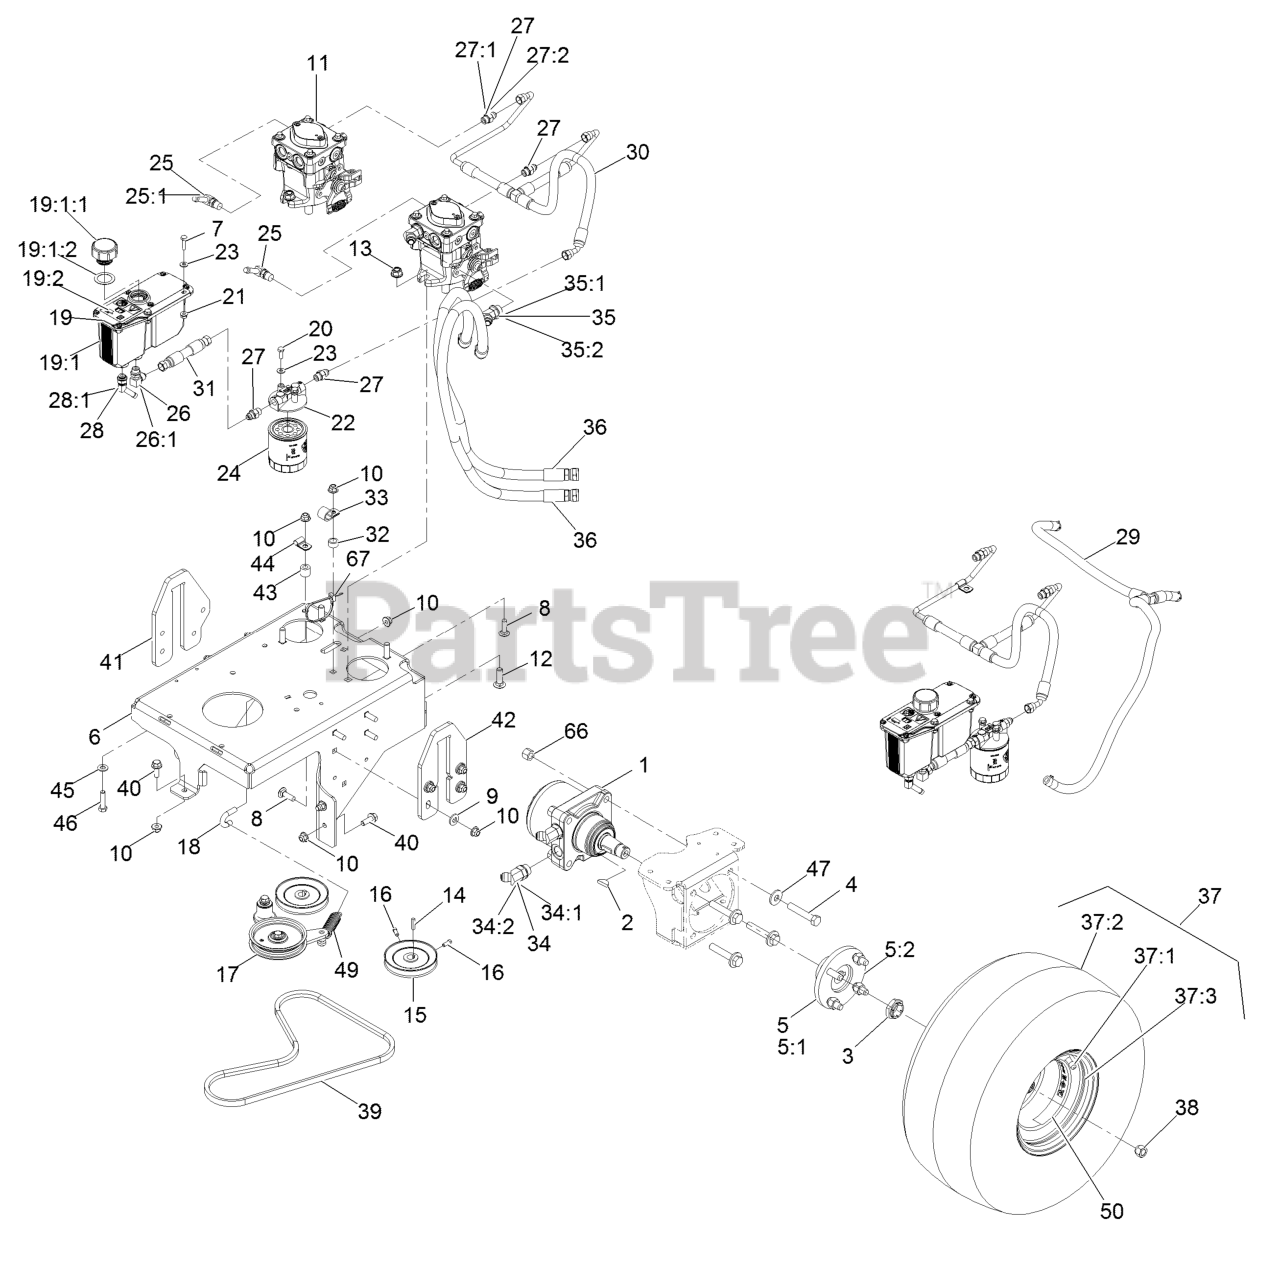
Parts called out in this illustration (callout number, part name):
1	Motor-Wheel
2	Key-Woodruff
3	Locknut
4	Screw-HH
5	Wheel Hub / Stud ASM
5:1	Hub-Wheel
5:2	Stud-Type, Drive
6	Base, Engine [red]
7	Screw-HH
8	Bolt-CARR
9	Washer-Belleville
10	Nut-HF, NI
11	Pump - Hydraulic
12	Bolt-CARR
13	Nut-HF, NI
15	Pulley-Pump
16	Screw-Set
17	Pump Idler ASM
18	Anchor, Spring
19	Reservoir ASM
19:1	Reservoir-HYD
19:1:1	Cap-Reservoir, HYD
19:1:2	Gasket-Cap
19:2	Decal-Warning
20	Screw-HH
21	Nut-HHF
22	Head-Filter
23	Washer-Flat
24	Element, Oil Filter
25	Fitting-Elbow, 90
25:1	O-Ring
26	Fitting-Elbow, 90 DEG
26:1	O-Ring
27	Fitting-Straight
27:1	O-Ring
28	Fitting-Barbed, 45 DEG
28:1	O-Ring
29	Tank Hose ASM
30	Hose Assembly - Charge
31	HYD Hose ASM
32	Spacer-Wheel
33	Clip-Loom
34	Fitting-HYD, 45 DEG
35	Fitting-HYD, 45 DEG
36	HYD Hose ASM
37	Wheel/Tire ASM
37:1	Rim-8 Inch
37:3	Stem-Valve
38	Nut-Lug
39	Belt-V, Lower PTO
40	Screw-HHF
41	Plate-Lift, RH
42	Plate, Lift LH
44	Clip-Tube
45	Washer-Flat
46	Screw-HH
47	Washer-Spring
49	Spring-Extension
50	Decal-Torque, Wheel Hub Lug
66	Nut-Lock, NI
67	Tie-Cable
